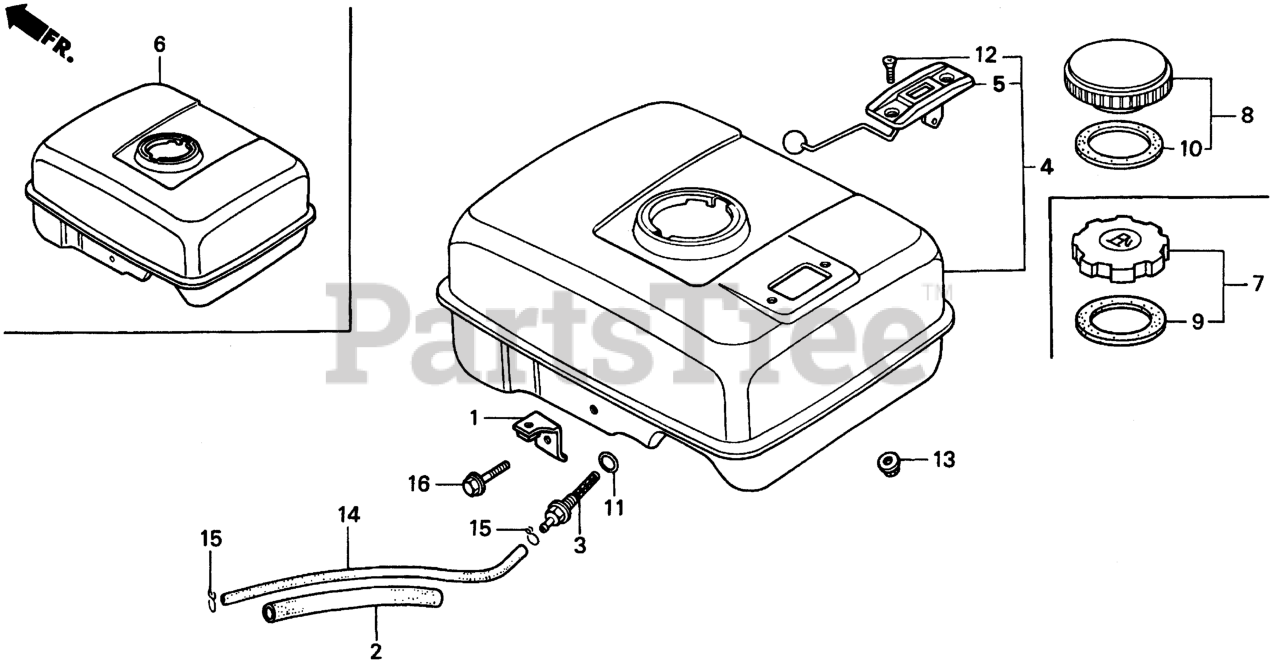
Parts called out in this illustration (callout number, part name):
1	STAY, ENGINE CONTROL COVER
2	RUBBER, SUPPORTER (107MM)
3	JOINT, FUEL TANK
6	TANK, FUEL *NH31* (MCKINLEY WHITE) Use up to Engine SN 3033315.
8	CAP, FUEL FILLER
8	CAP, FUEL FILLER (BLACK) Use up to Engine SN 2115700.
8	CAP, FUEL FILLER (CHROME PLATED)
8	CAP COMP
10	GASKET, FUEL FILLER CAP (39X58X3) (NOT AVAILABLE)
10	GASKET, FUEL FILLER CAP Use from Engine SN 1543258.
10	GASKET, FUEL FILLER CAP (39X58X3)
11	O-RING (14MM) (ARAI) Use up to Engine SN 2949254.
13	NUT, FLANGE (6MM)
14	BULK HOSE, FUEL (4.5X3000) (Honda Code 5137104). (4.5X140)
15	CLIP, TUBE (B8)
16	BOLT, FLANGE (6X25)
